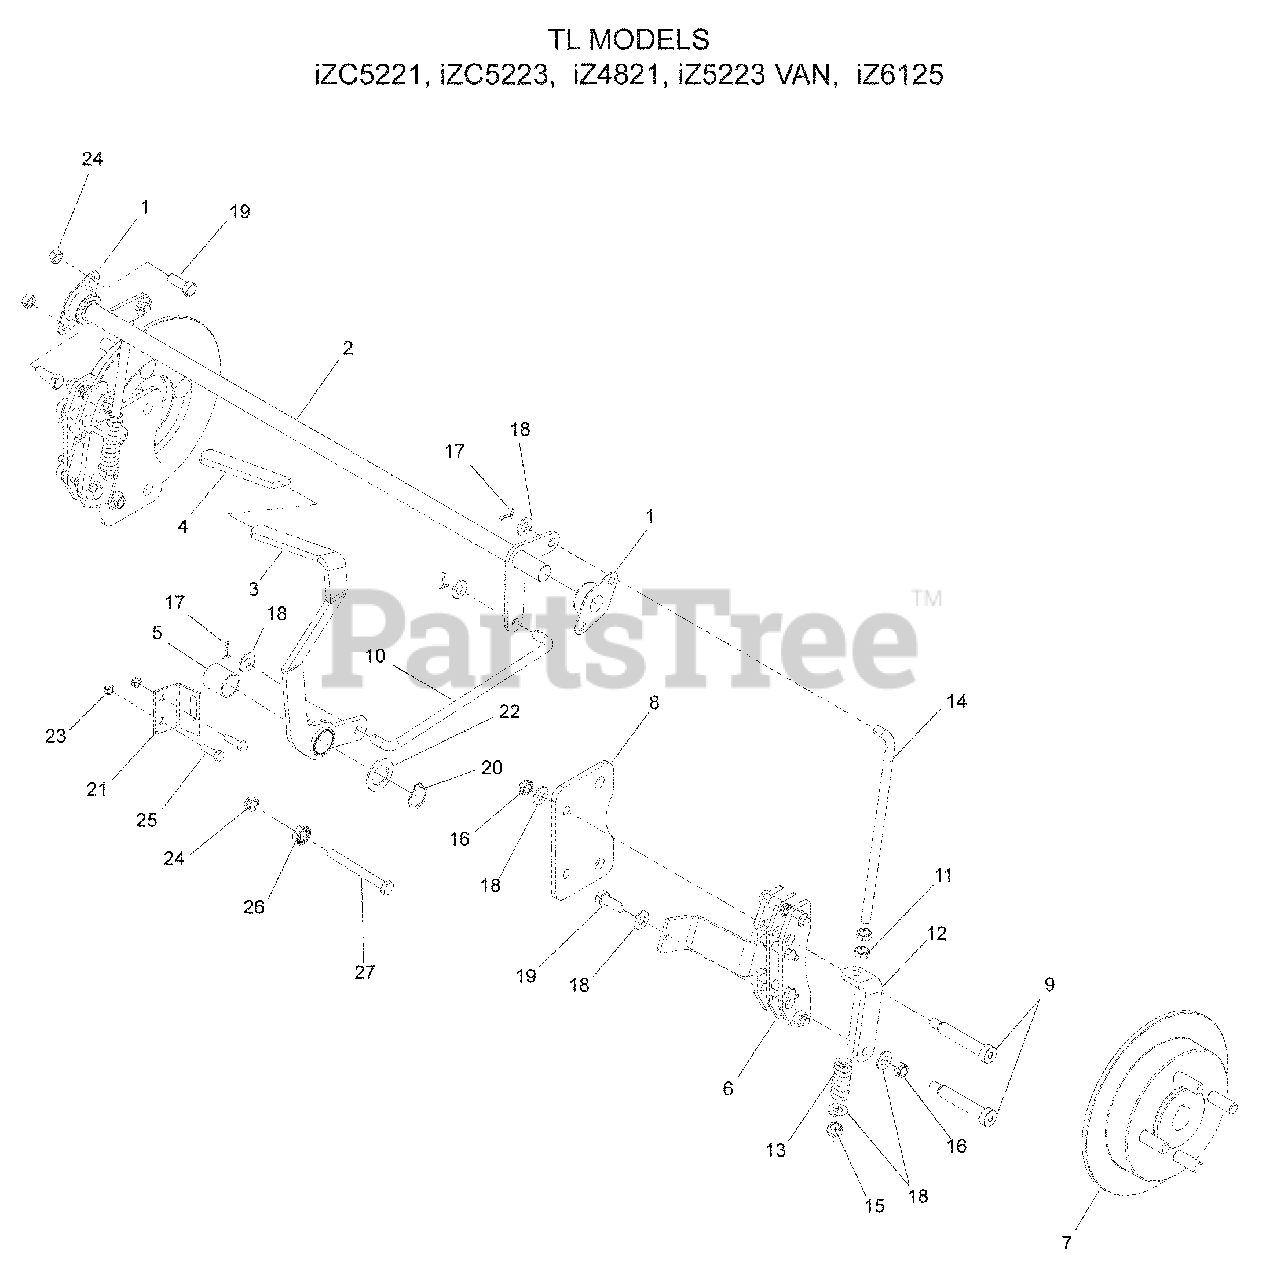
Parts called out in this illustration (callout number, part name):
1	BEARING, FLANGED
2	CROSS, SHAFT BRAKE
3	LEVER, BRAKE
4	GRIP, PARK BRAKE
8	PLATE, BRAKE
9	SCREW, 3/8-16 x 2½, SKT
10	LINKAGE, BRAKE
11	NUT 3/8-24, JAM
14	LINKAGE, REAR BRAKE
15	NUT 3/8-24 CENTERLOCK
16	NUT 3/8-16 THIN NYLOC
17	PIN COTTER, 3/32 x ¾
18	WASHER 3/8 SAE FLT
19	HCS 3/8-16 x 1
20	RING, RETAINING EXT 7/8
23	NUT ¼-20 HEX NYLOC
24	NUT 3/8-16 HEX NYLOC
25	HCS ¼-20 x ¾
26	NUT 3/8-16 WHIZLK
27	HCS 3/8-16 x 2½
